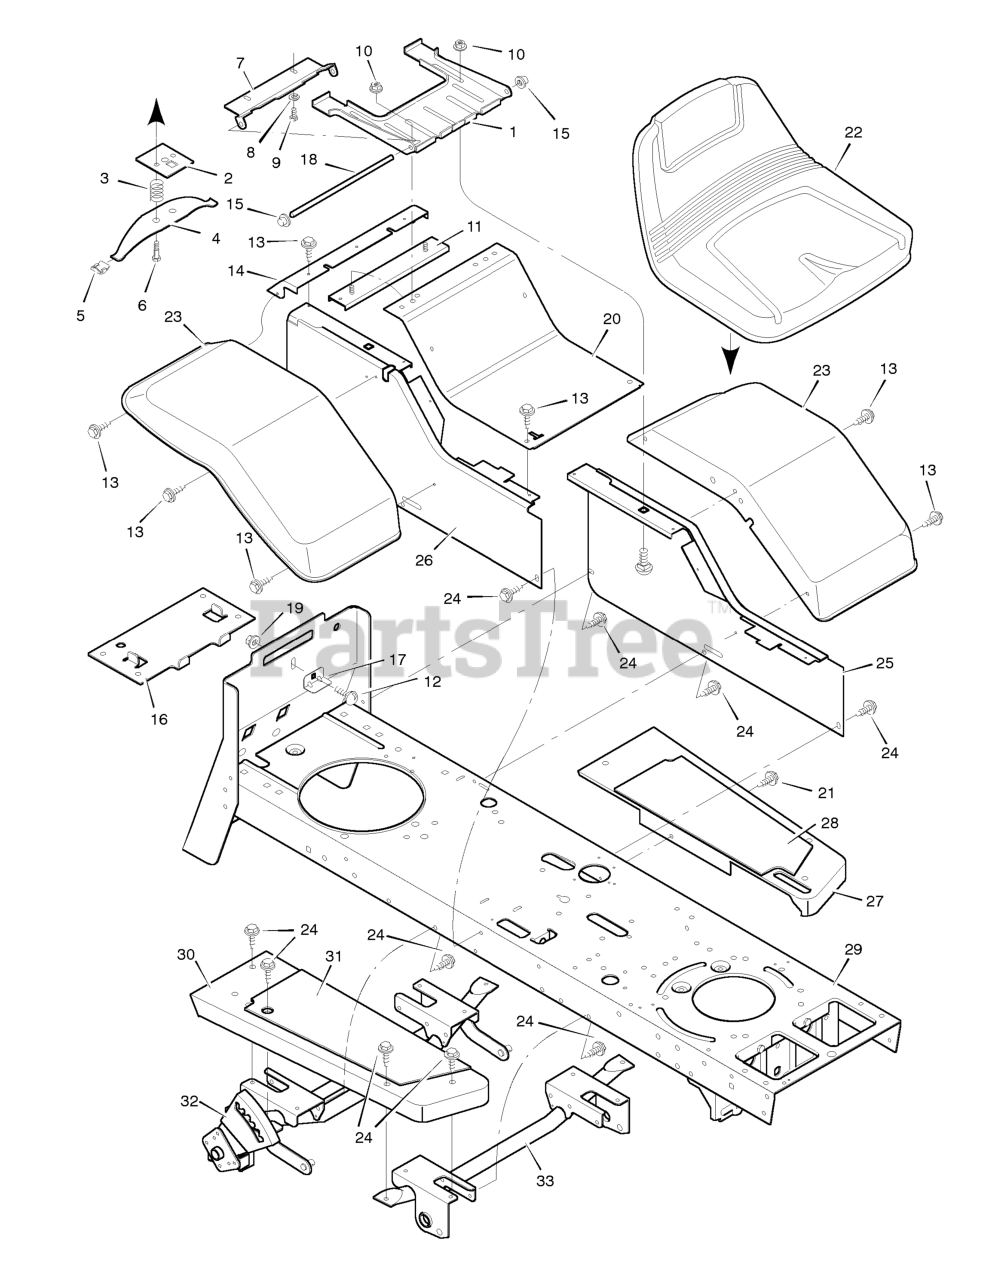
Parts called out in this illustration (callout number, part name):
1	Bracket, Seat
2	Plate Assembly, Switch
3	Spring, Compression
4	Spring, Seat
5	Glide, Spring
6	Bolt, Shoulder
7	Support, Seat
8	Lockwasher
9	Bolt, Hex
10	Locknut, Flange
11	Channel Assembly
12	Bolt, Carriage
14	Insert, Rear
15	Push On Cap
16	Support, Battery
17	Clamp, Battery
18	Rod, Pivot
19	Locknut
20	Panel, Top
21	Fastener, Panel
25	Panel, Left
26	Panel, Right
27	Running Board, Left
28	Mat, Left
29	Frame Channel
30	Running Board, Right
31	Mat, Right
32	Lifter and Support Assembly
33	Support Assembly, Front
